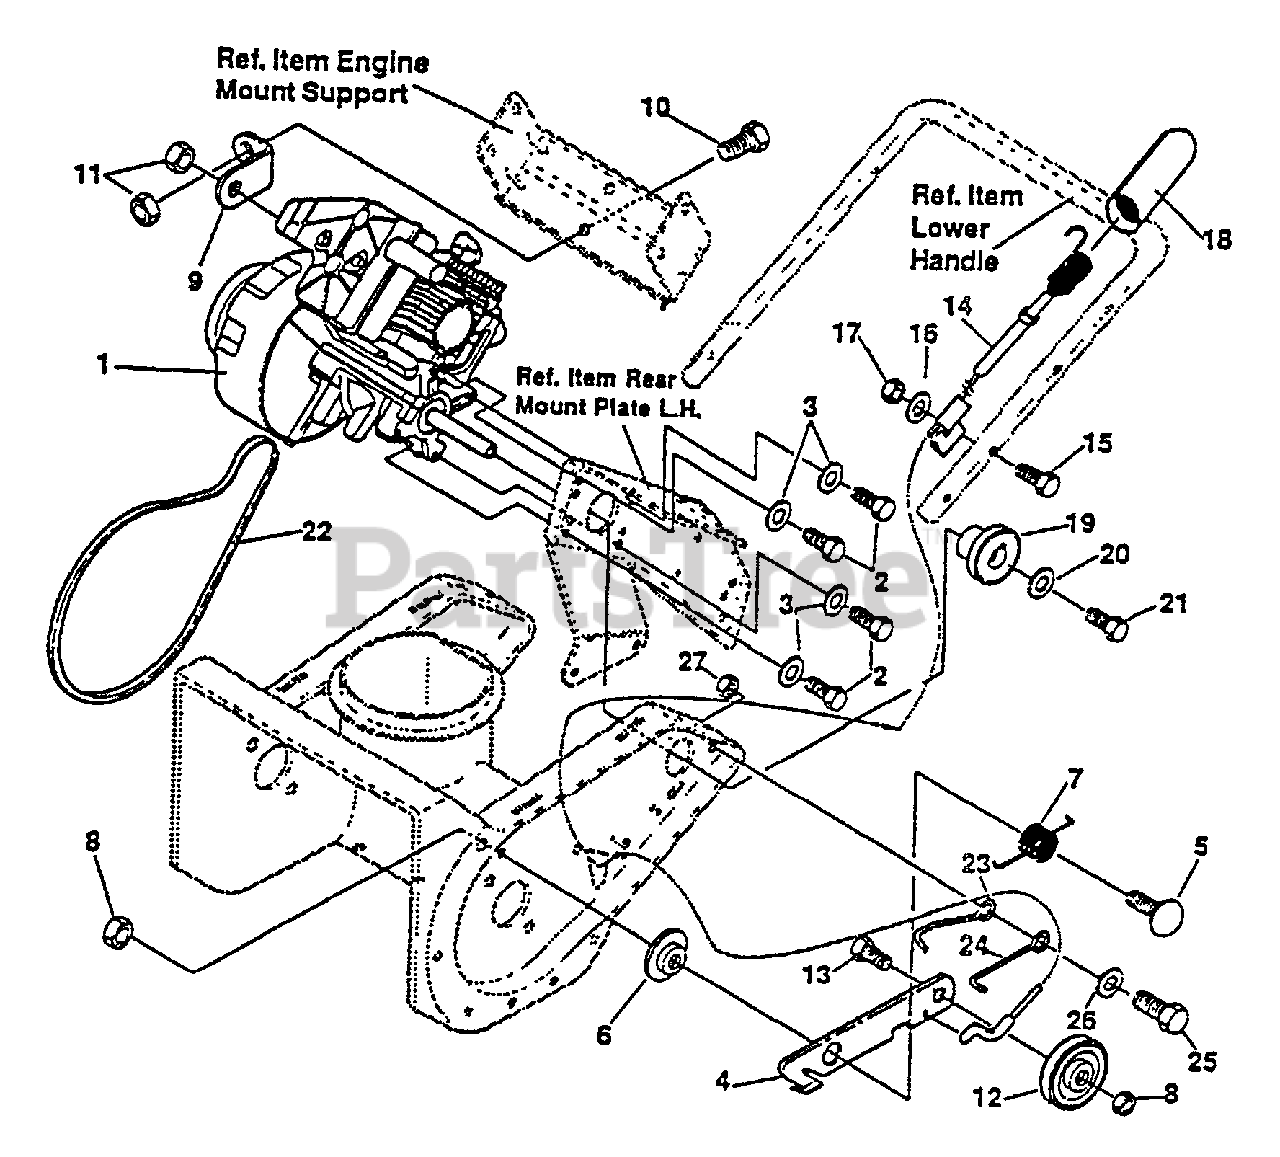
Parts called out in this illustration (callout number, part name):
1	TECUMSEH HSK50-67337L
1	TECUMSEH HSK840-8220A
1	TECUMSEH HSK840-8217A
2	SCREW
3	LOCKWASHER
4	BRACKET, IDLER ARM
5	BOLT, IDLER ARM
6	SPACER
7	SPRING, BRAKE
8	LOCKNUT - 3/8-16
9	SUPPORT, ENGINE
10	SCREW - 5/16-18 X 1/2"
11	NUT - 5/16-18
12	IDLER PULLEY, 1.88X.5X.38
13	BOLT - 3/8-16 X 1.25"
14	CABLE, DRIVE CONTROL
15	SCREW - 1/4-20 X 1-1/2"
16	WASHER
17	NUT - 1/4-20
18	COVER, CABLE HOLDER
19	PULLEY HALF, 3L, 2.00
20	WASHER
21	SCREW - 5/16-24 X 7/8"
22	BELT, V3LX35, .048 D
23	GUIDE, BELT .381DX2.66
24	GUIDE, BELT .381DX3.30 OFF
25	SCREW - 3/8-16 X 1"
26	WASHER
27	NUT - 3/8-16
